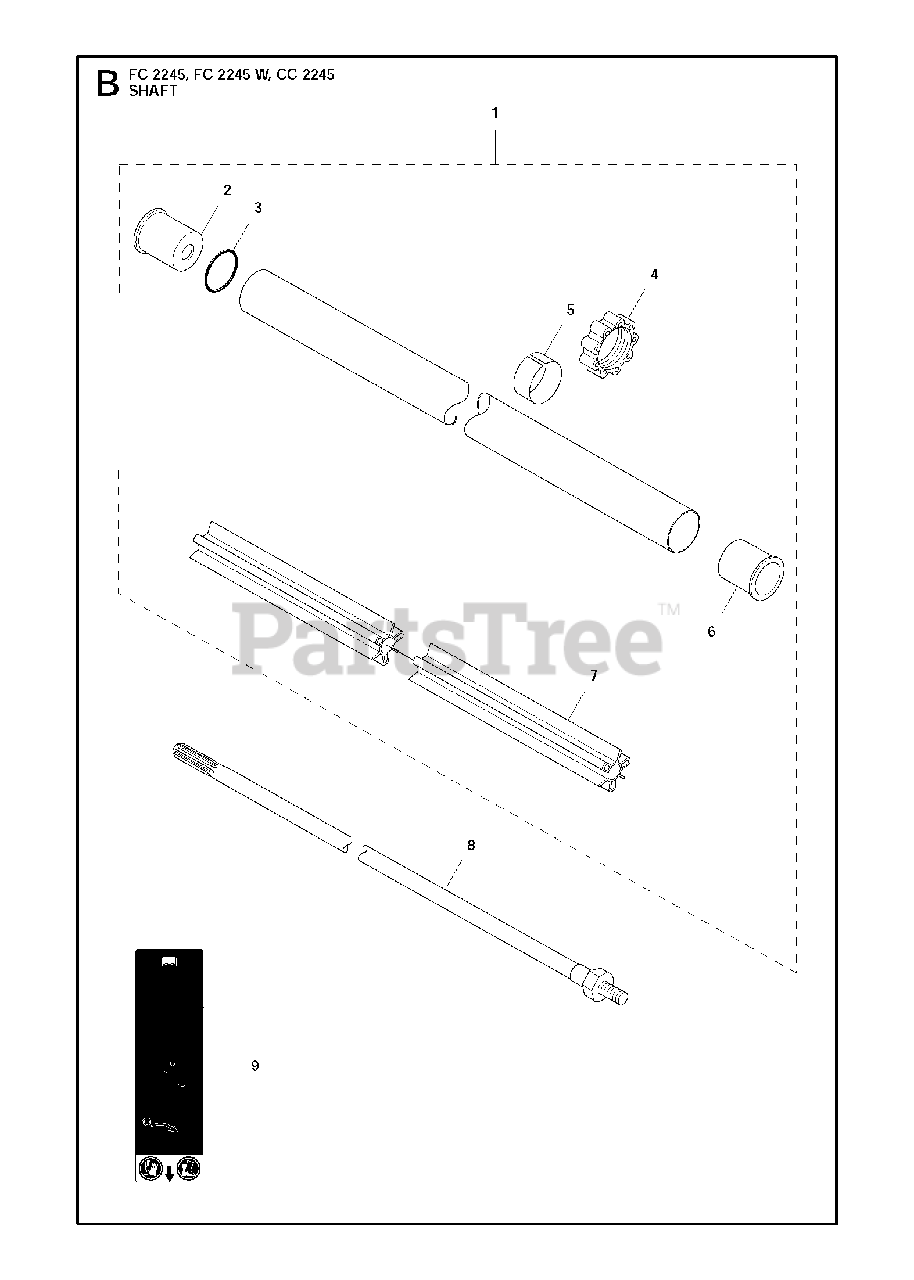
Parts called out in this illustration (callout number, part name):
1	RP TUBE ASSY
1	TUBE ASSY
2	SPACER SLEEVE
4	MOVEMENT LIMITER
5	%BAND
6	SPACER SLEEVE
7	BEARING SHAFT
8	SHAFT
8	DRIVE SHAFT
9	WARNING DECAL
